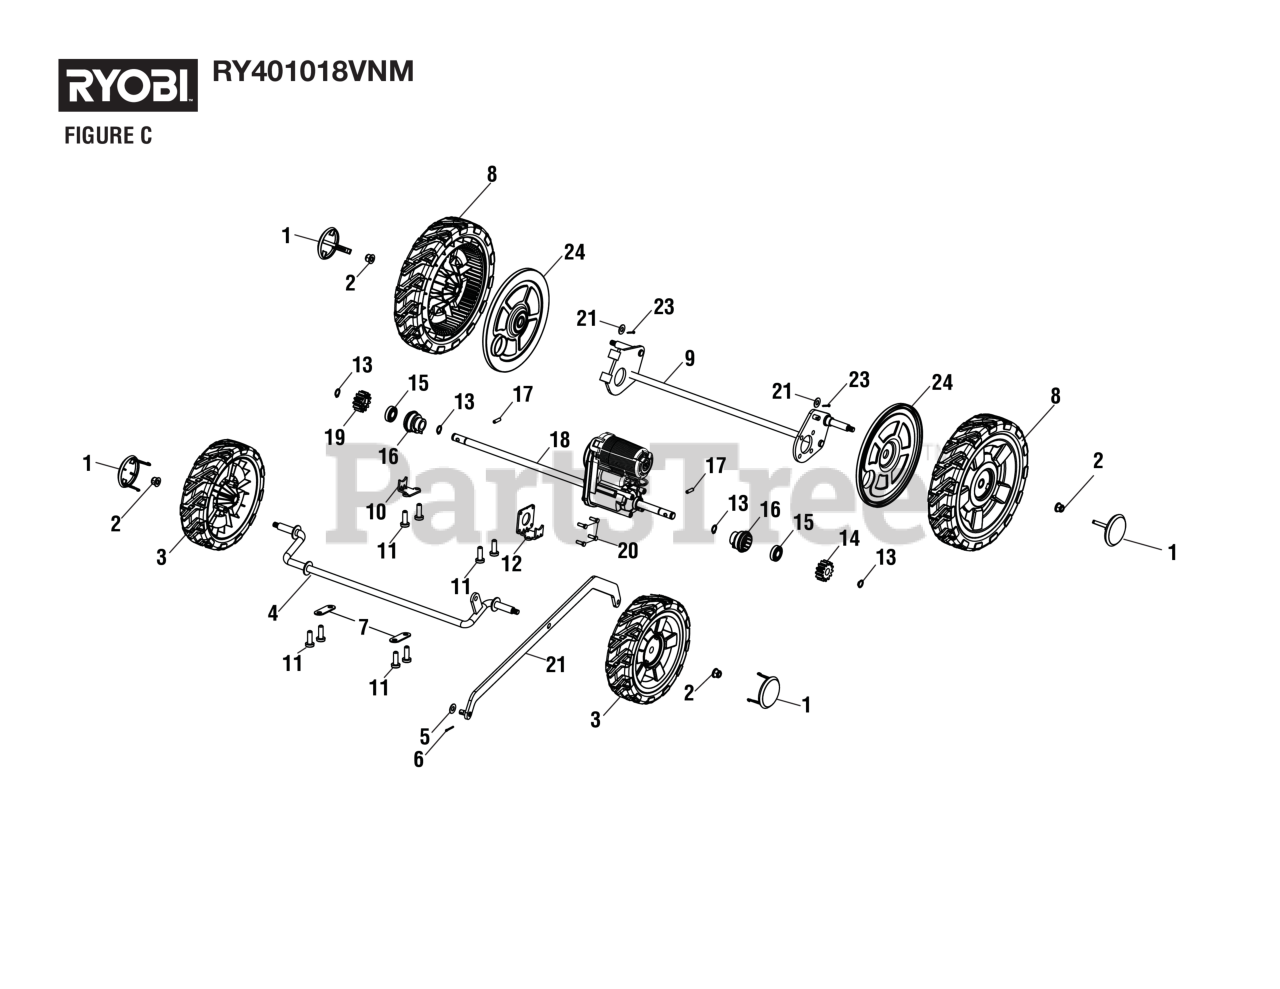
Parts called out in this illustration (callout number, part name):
1	Wheel Hub Cap
2	Flange Lock Nut (M8 x 1.25 mm)
3	8 in. Wheel
4	Front Wheel Axle
5	Washer (ID8.4 x OD18 x 1t)
6	Cotter PinÏ? (2.5)
7	Front Axle Press Plate
8	10 in. Wheel w/Bushing Assembly
9	Rear Wheel Axle
10	Rear Axle Mount Plate
11	Screw (1/4-15 x 3/4 in., T30 Torx Pan Hd.)
12	Transmissions Mounting Plate
13	Retaining Ring
14	Drive Gear, Left
15	Ball Bearing (OD28.6 x ID12.7 x 8)
16	Rear Axle Bearing Cup
17	Drive Gear, Right
18	GT Transmissions Assembly
19	Drive Gear, Right
20	Screw (M5 x 14.5 mm)
21	Connecting Bar
22	Washer (ID8.4 x OD18 x 1t)
23	Cotter PinÏ? (2.5)
24	Wheel Cover
